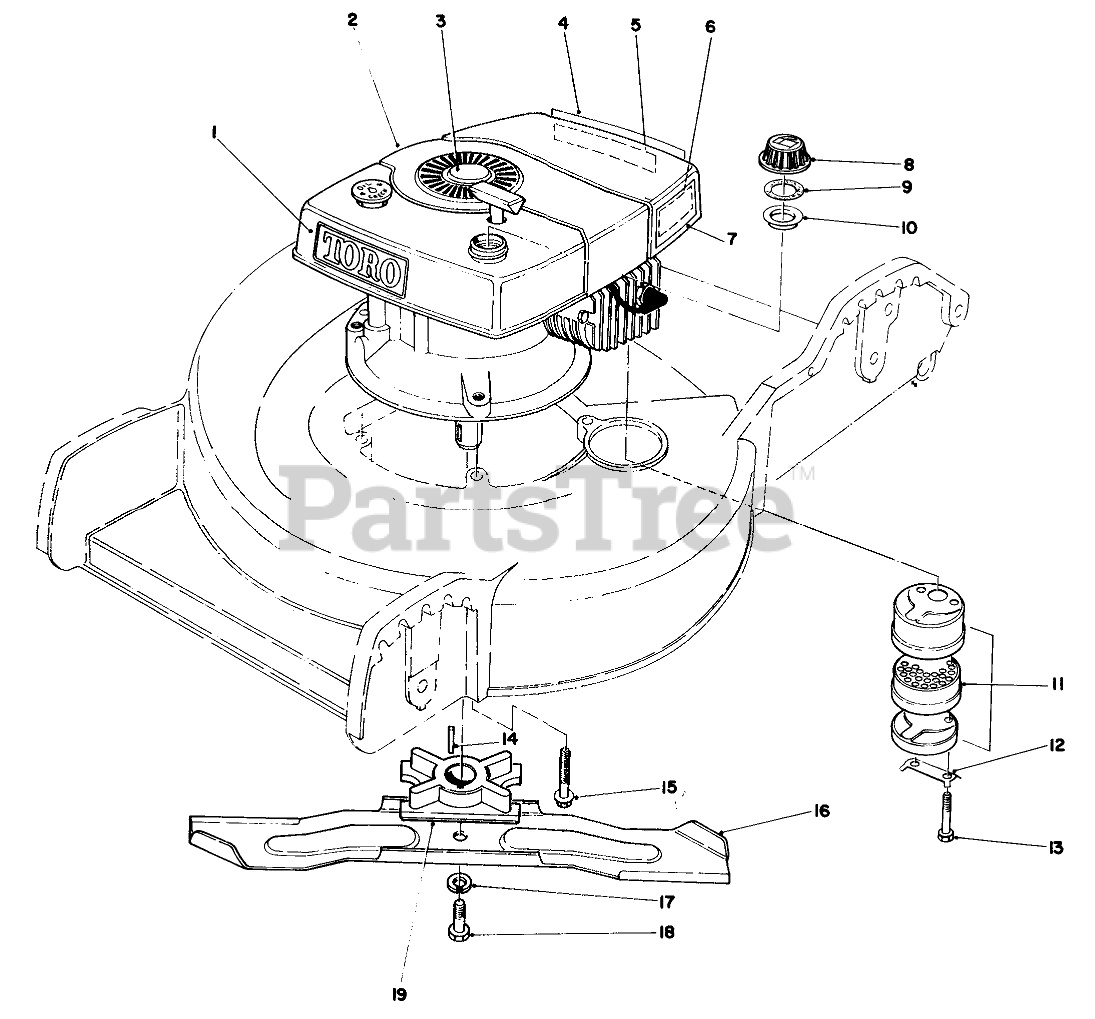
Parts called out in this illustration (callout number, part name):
1	Decal Tow
2	Engine
3	Plug Button
4	Decal-Primer Bulb
5	Decal Maintenance
6	Decal-Maintenance
7	Decal-Maintenance
8	Gas Cap (Incl. Ref. #9 & 10)
9	GASKET
10	GAS CAP BAFFLE
11	Muffler Assembly (Incl. Ref. #12 & 13)
12	CLIP - LOCKING
13	SCREW-HH
14	KEY-SQUARE
15	3/8-16 X 2 CAPSCREW
16	Blade
17	WASHER-LOCK
18	SCREW-HH
19	Blade Retainer
